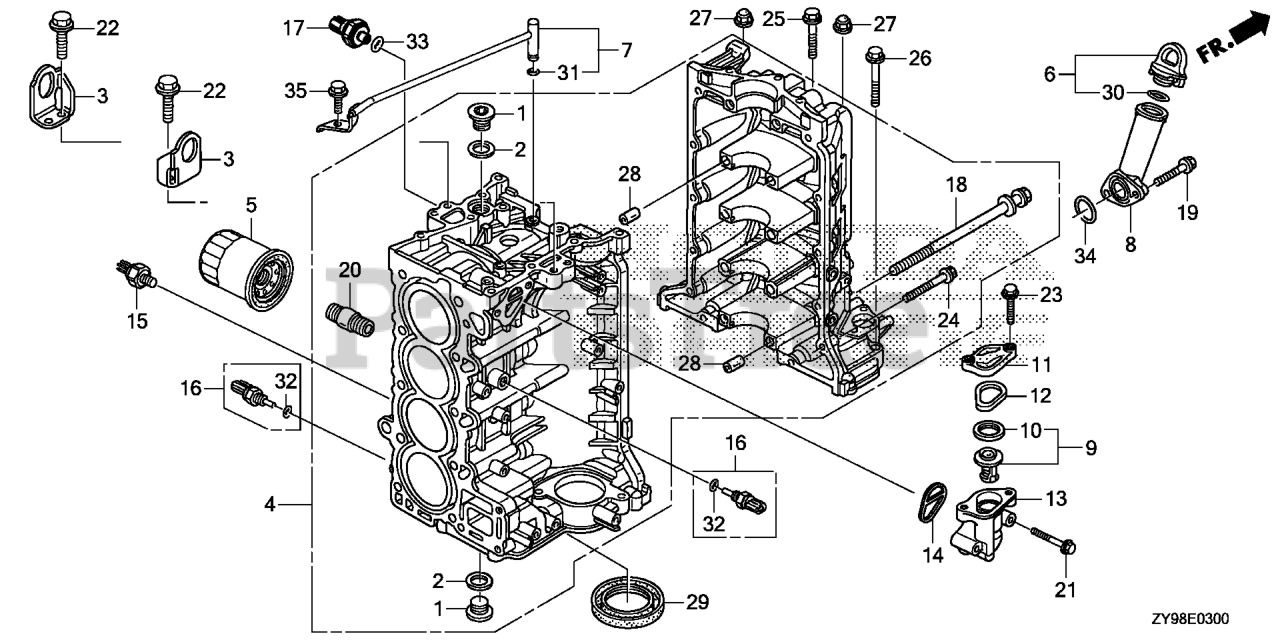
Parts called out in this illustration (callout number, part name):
1	BOLT, SEALING (24MM)
2	WASHER, SEALING (24MM)
3	HANGER, ENGINE
4	BLOCK (M000) *NH8*
5	FILTER, OIL (FILTECH TOYO ROKI) (SOLD IN MULTIPLES OF 30)
5	FILTER, OIL (HONEYWELL) (SOLD IN MULTIPLES OF 30)
5	FILTER, OIL
6	CAP ASSY., OIL FILLER
8	EXTENSION, OIL FILLER
9	THERMOSTAT ASSY.
10	RUBBER, RING
11	COVER, THERMOSTAT
11	COVER THERMOSTAT
12	O-RING, THERMOSTAT COVER
13	CASE, THERMOSTAT
14	PKG, THERMOSTAT CASE
15	SENSOR, KNOCK
16	SENSOR ASSY., WATER TEMPERATURE
17	SENSOR, OIL PRESSURE
18	BOLT-WASHER (10X105)
19	BOLT, FLANGE (6X25)
20	HOLDER, OIL FILTER
21	BOLT, FLANGE (6X45)
22	BOLT, FLANGE (8X20)
23	BOLT, FLANGE (6X22)
24	BOLT, FLANGE (6X32)
25	BOLT, FLANGE (8X35)
26	BOLT, FLANGE (8X45)
27	NUT, FLANGE CAP (8MM)
27	NUT (8MM)
28	PIN, DOWEL (12X14)
29	OIL SEAL (80X98X10)
30	O-RING (18.1X3.6)
31	O-RING (6.5X1.5)
32	O-RING (9.5X1.9)
33	O-RING (13X1.5) (ARAI)
34	O-RING (28.3X2.4) (NOK)
35	BOLT, FLANGE (6X14)
